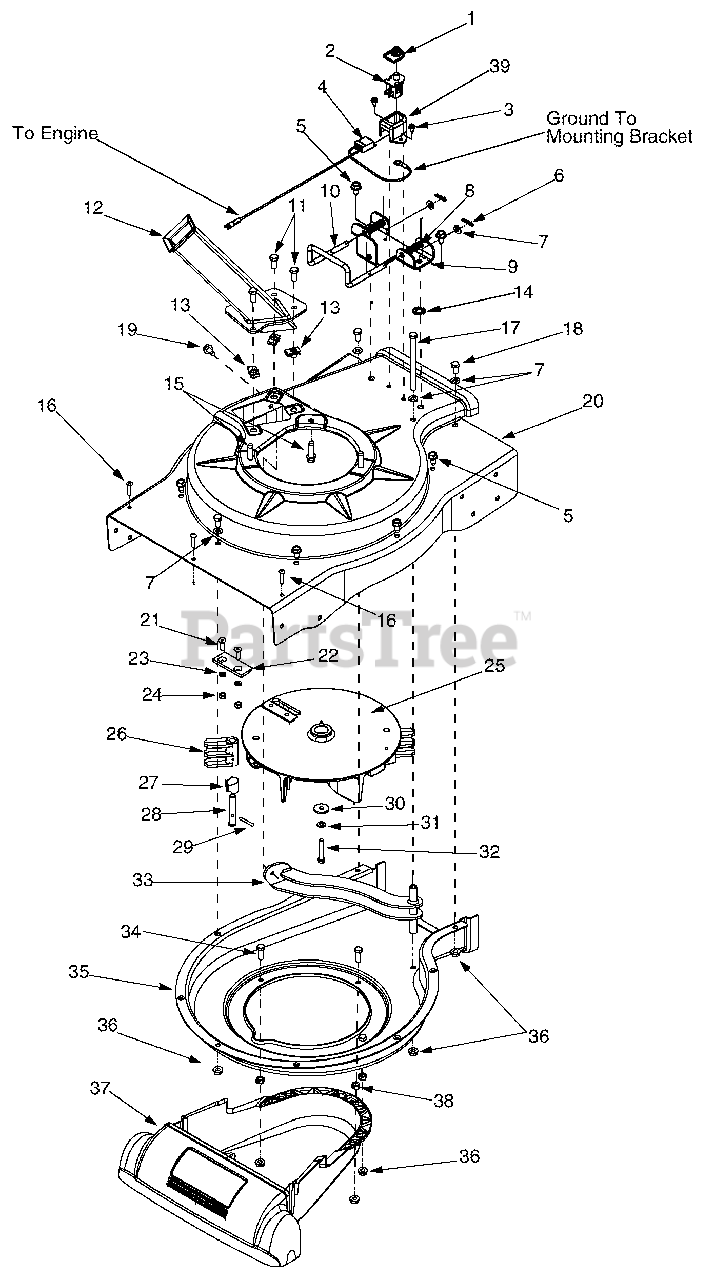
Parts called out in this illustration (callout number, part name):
1	Switch Cover
2	Safety Switch
3	Hex Washer Screw #10-16 x .50
4	Wire Harness
5	Hex Washer Screw 5/16-18 x .625
6	Cotter Pin
7	Flat Washer.330 ID x.630 OD
8	Compression Spring
10	Lock Rod
11	Hex Cap Screw 5/16-18 x .75
13	U-Clip Lock Nut 5/16-18
14	External Lock Washer 5/16
15	Hex Washer Screw 3/8-16 x 1.25
16	Screw #12-16 x 1.0
17	Hex Cap Screw 5/16-18 x 4.5
18	Hex Cap Screw 5/16-18 x .625
19	Hex Washer Screw 5/16-18 x .625
22	Chipper Blade
23	Lock Washer 5/16
24	Hex Lock Nut 5/16-24
25	Impeller Assembly
26	Flail Blade
27	Pin Clip
28	Clevis Pin
29	Spiral Pin
30	Flat Washer.375 ID x 1.25 OD
31	Lock Washer 3/8
32	Hex Cap Screw 3/8-24 x 2.0
34	Hex Cap Screw 5/16-18 x .875
36	Lock Nut 5/16-18
37	Nozzle Cover
38	Lock Nut 5/16-18
39	Safety Switch Cover
